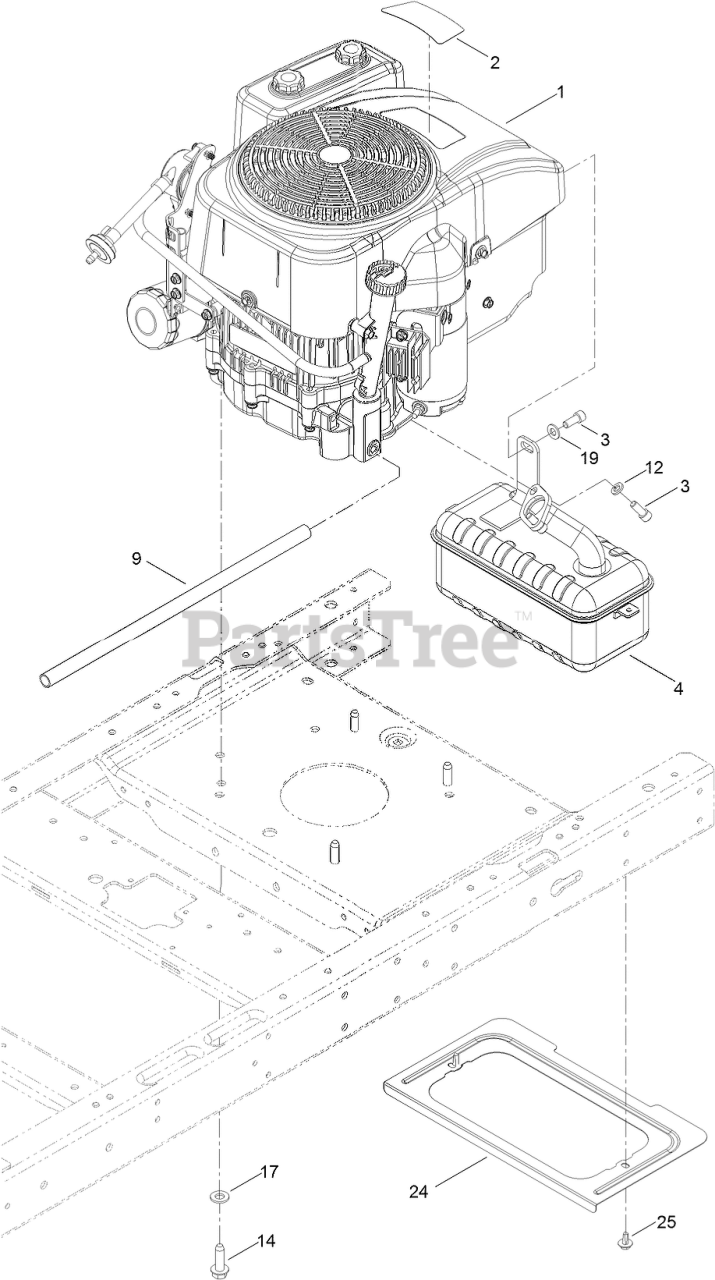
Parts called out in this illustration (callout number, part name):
1	ENGINE-1P92F-1
2	DECAL-ENGINE
3	SCREW-HSH
4	MUFFLER
9	TUBE-DRAIN, OIL
12	WASHER-LOCK
14	SCREW-TAPTITE
17	WASHER-FLAT
19	WASHER-PLAIN
24	SHIELD-HEAT
25	SCREW-HHFTF
